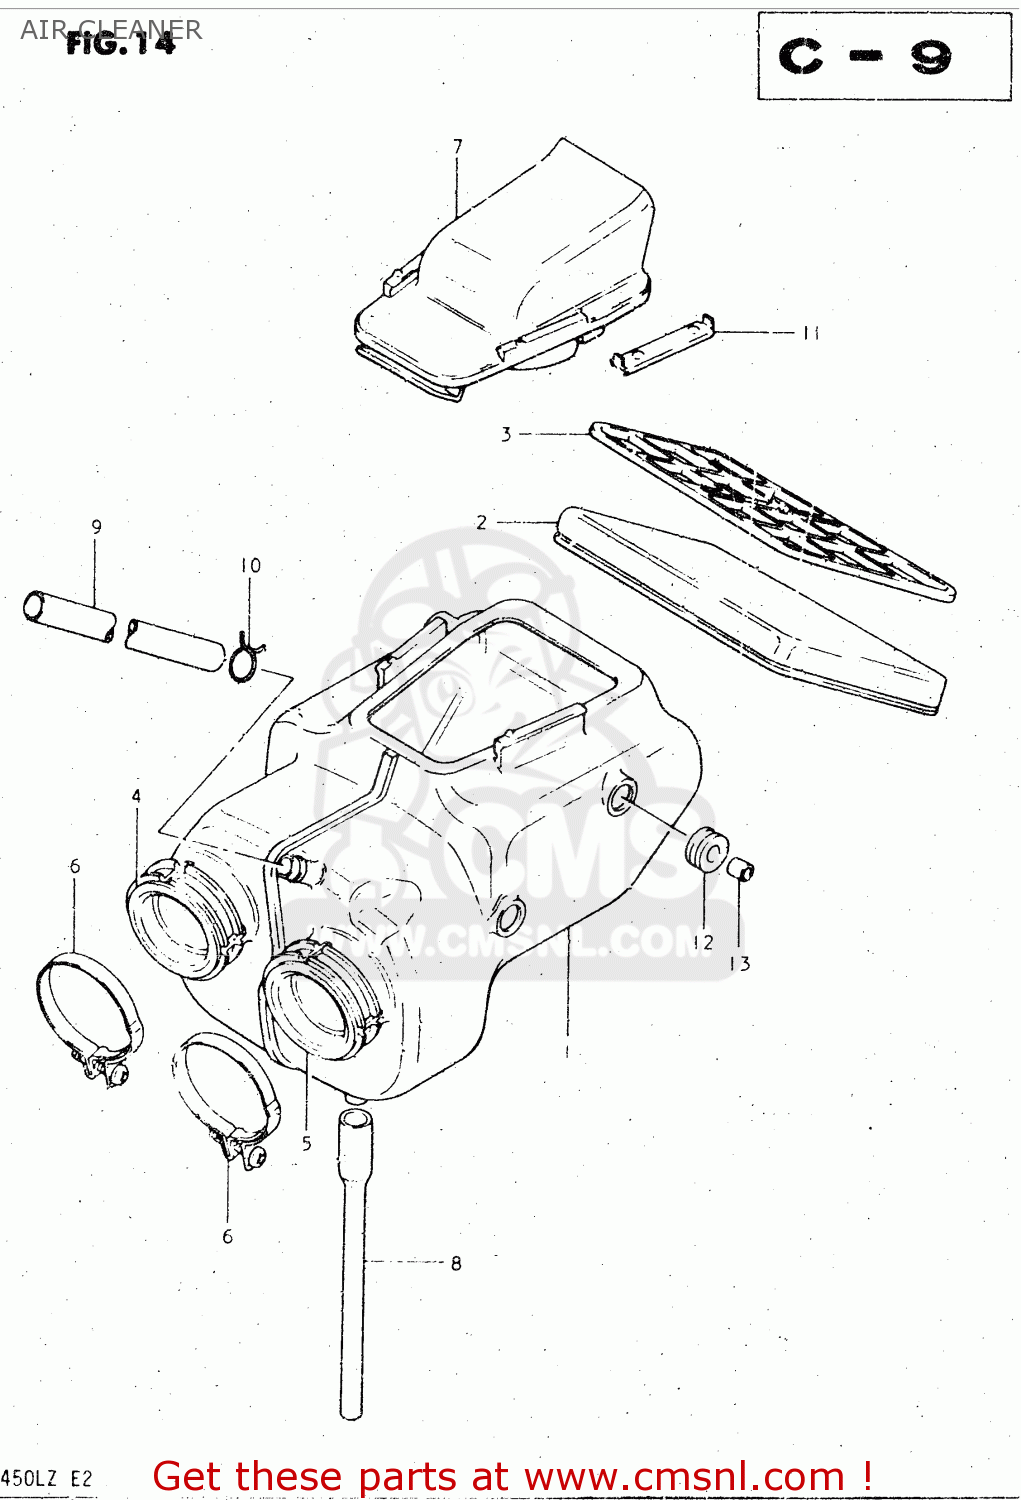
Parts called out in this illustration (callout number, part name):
1	CLEANER ASSEMBLY,AIR
2	FILTER
3	HOLDER NO.2
4	OUTLET,R
5	OUTLET,L
6	CLAMP
7	CAP
8	DRAIN TUBE
9	HOSE
10	CLAMP
11	SLIDER
12	CUSHION
13	SPACER(6.1X9X7.5)
